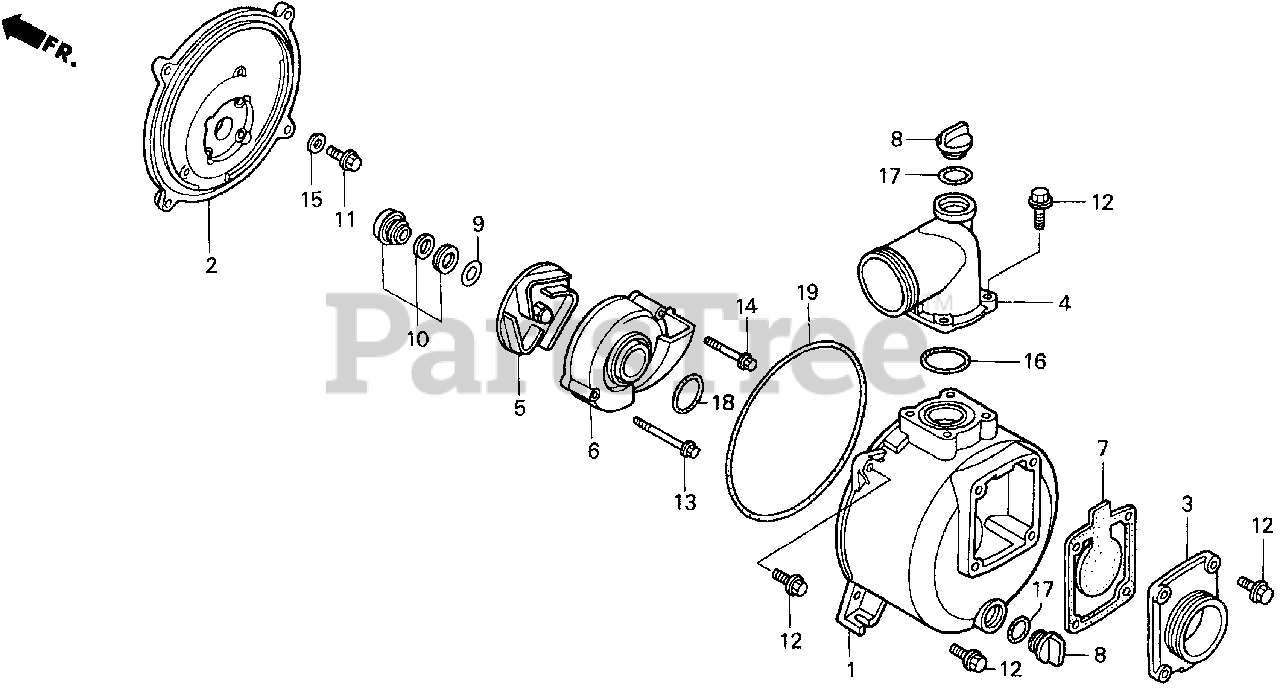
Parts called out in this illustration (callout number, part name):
2	COVER, CASING
3	PIPE, INLET
4	PIPE, OUTLET
6	CASE, VOLUTE
7	VALVE, IN.
8	CAP, FILLER
9	SHIM A, ADJUSTER (0.3) (STD)
9	SHIM B, ADJUSTER (OS) (0.5)
10	SEAL ASSY., MECHANICAL
11	BOLT, FLANGE (8X28)
12	BOLT, FLANGE (8X25)
13	BOLT, FLANGE (6X60)
14	BOLT, FLANGE (6X50)
15	WASHER (8MM)
16	O-RING (86X3.5)
17	O-RING (24X3.5)
18	O-RING (70X5.7)
19	O-RING (225X3.5)
